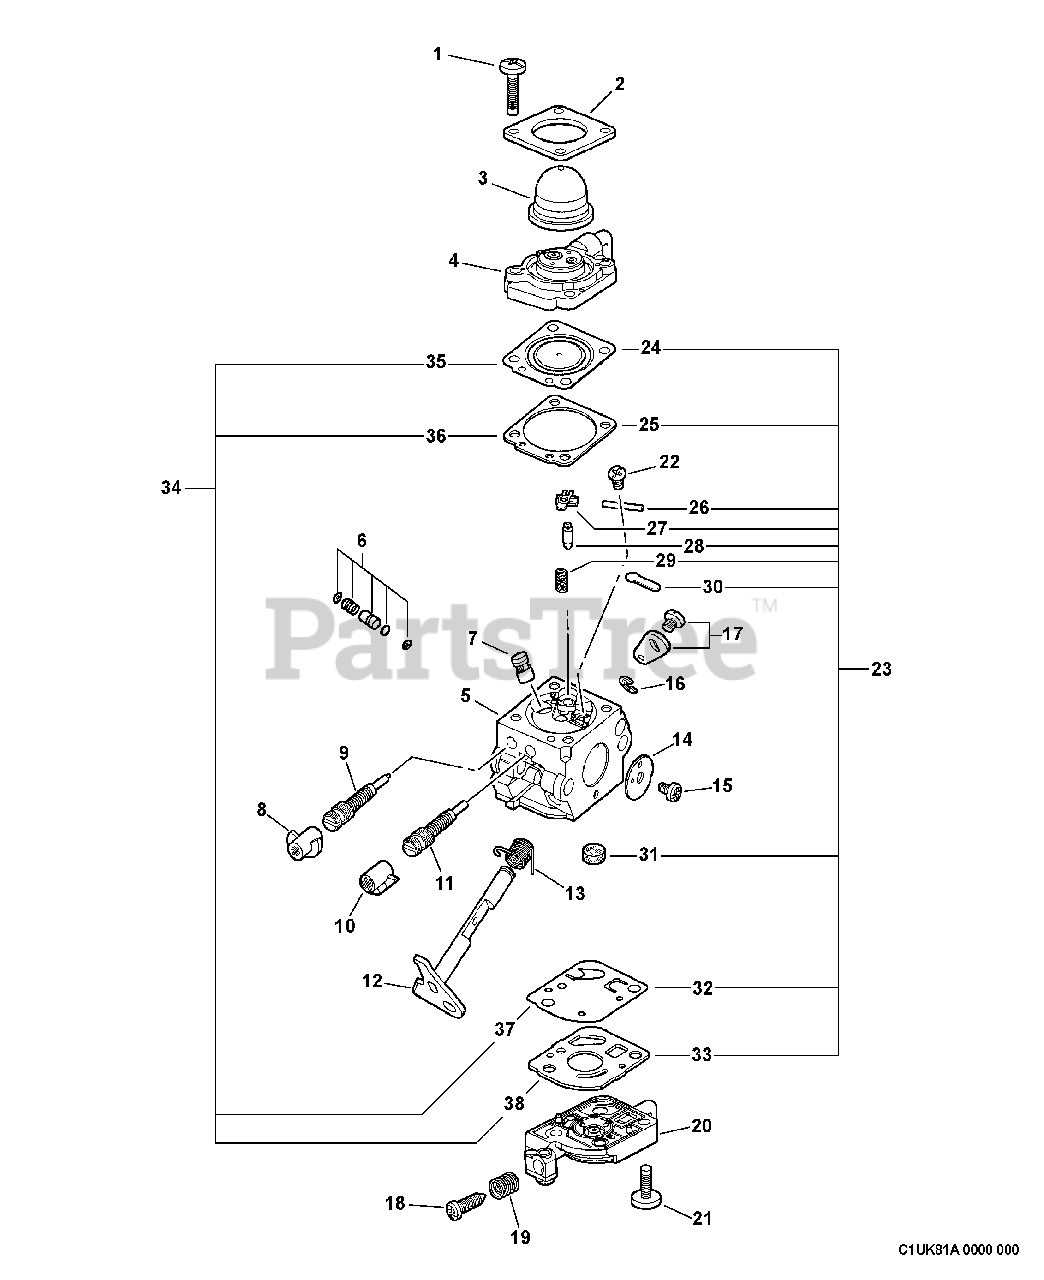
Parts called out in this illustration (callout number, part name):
2	RETAINER, PURGE BULB
3	BULB, PURGE
4	BODY ASSY, PUMP
5	BODY, CARBURETOR
6	PUMP KIT
7	NOZZLE, CHECK VALVE
8	CAP, LIMITER - RED
9	NEEDLE, HIGH SPEED
10	CAP, LIMITER - WHITE
11	NEEDLE, MIXTURE
12	SHAFT, THROTTLE
13	SPRING, THROTTLE RETURN
14	VALVE, THROTTLE
17	THROTTLE LEVER KIT
18	SCREW, THROTTLE ADJUST
20	COVER, FUEL PUMP
23	REBUILD KIT
24	DIAPHRAGM, METERING
25	GASKET, DIAPHRAGM
26	PIN, METERING LEVER
27	LEVER, METERING
28	VALVE, INLET NEEDLE
29	SPRING, METERING LEVER
30	PLUG, WELCH
31	STRAINER
32	DIAPHRAGM, PUMP
33	GASKET, PUMP
34	GASKET / DIAPHRAGM KIT
35	DIAPHRAGM, METERING
36	GASKET, DIAPHRAGM
37	DIAPHRAGM, PUMP
38	GASKET, PUMP
